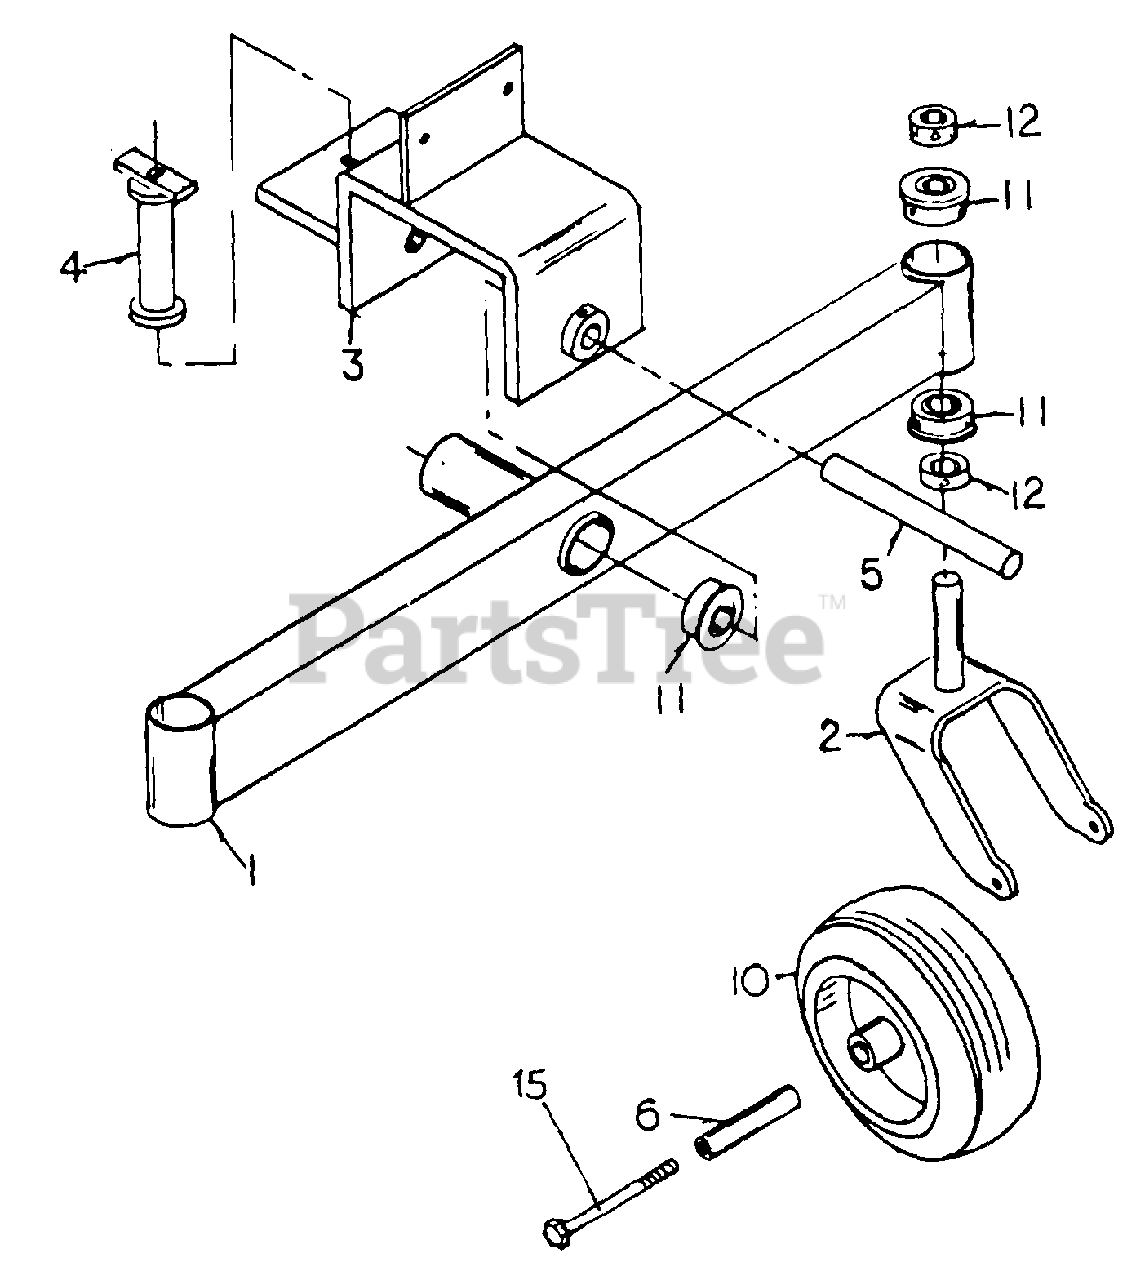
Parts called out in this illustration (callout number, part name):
1	Dual Tail Wheel Axle
2	Dual Tail Wheel Fork
3	Dual Tail Wheel Mount
4	Dual Tail Wheel Tube Block
6	Tail Wheel Axle
10	Tail Wheel Assembly
12	Set Collar, 1"
15	Hex Capscrew, 1/2-13 x 6 1/2"
